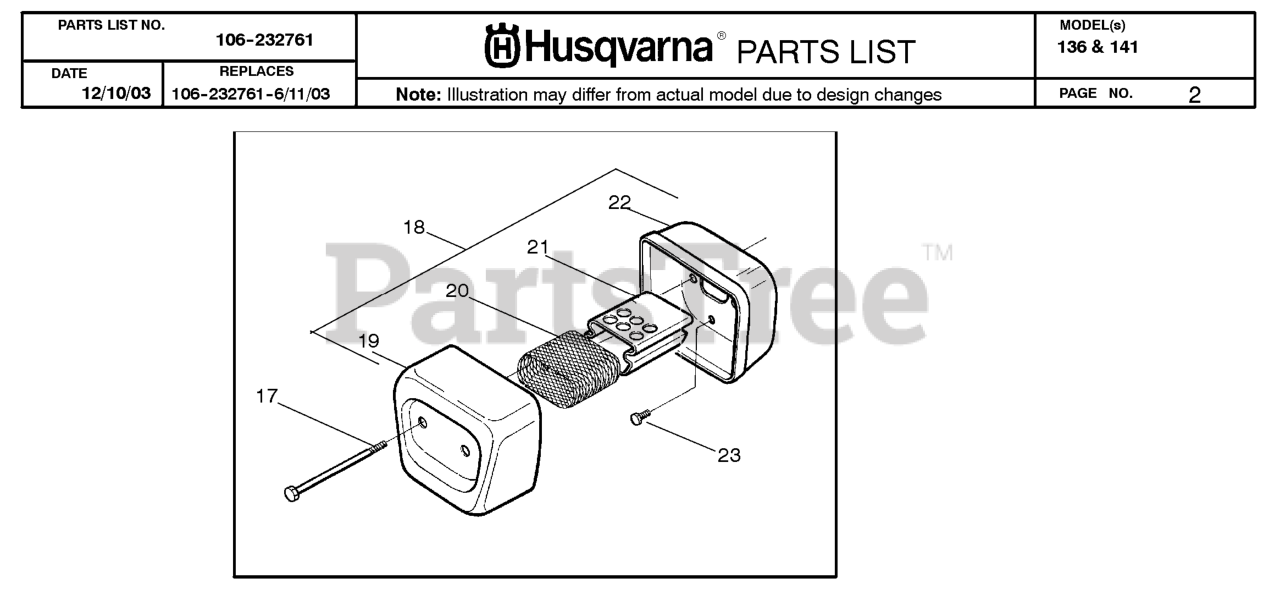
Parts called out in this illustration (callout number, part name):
18	MUFFLER KIT
19	SILENCER COVER
20	SPARK ARRESTOR 36/41
21	FLAME PROTECTOR
22	SILENCER BODY
23	BOLT-MUFFLER(SUPPORT)
